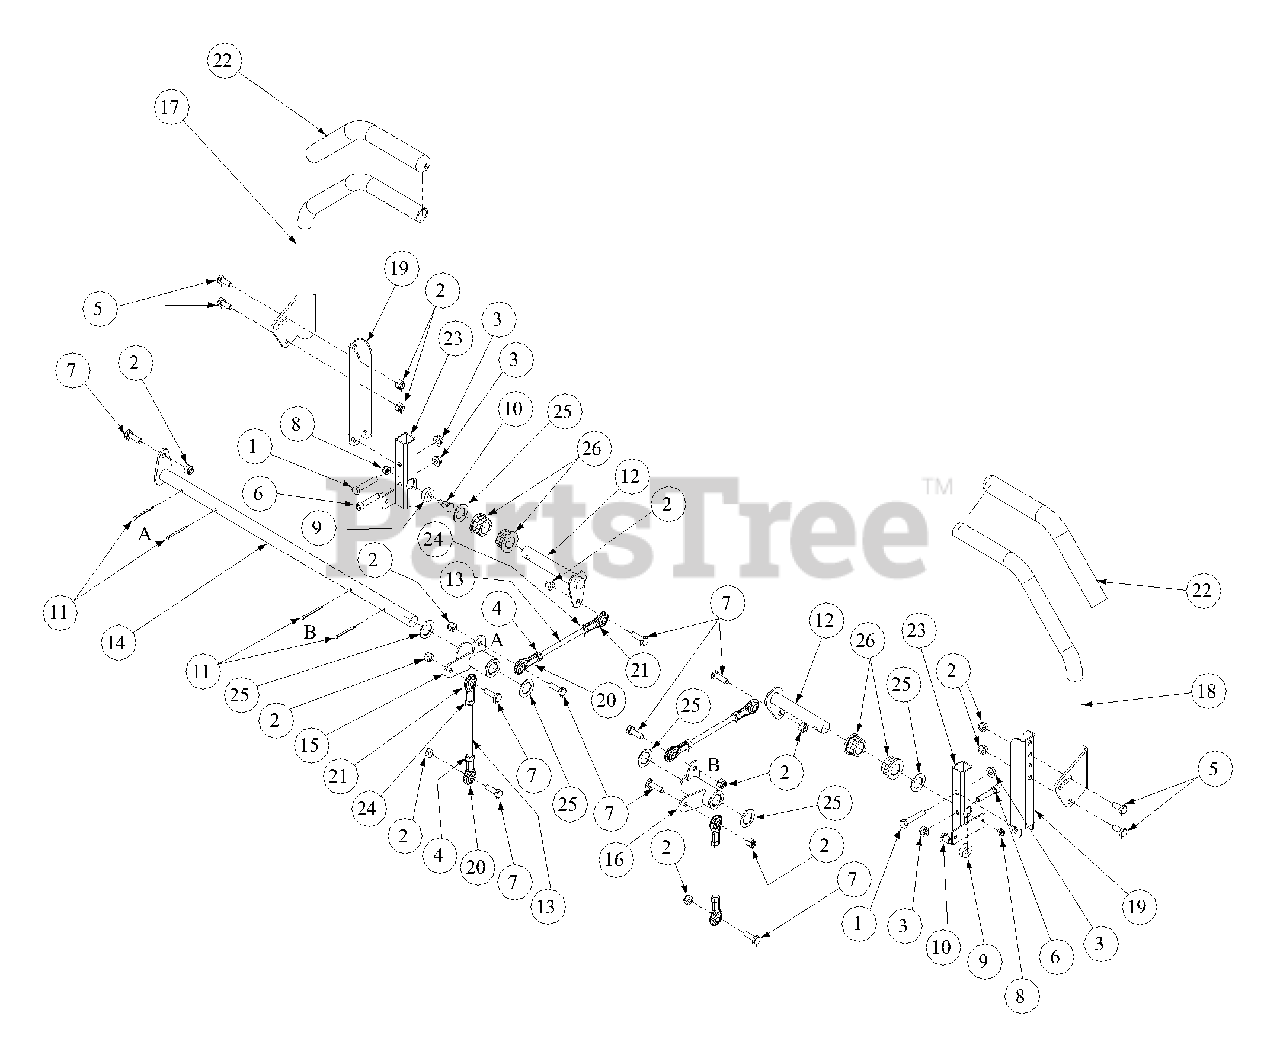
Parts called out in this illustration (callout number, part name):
1	Hex Cap Screw, 5/16-18 x 1-3/4
2	Nut, 5/16-18, Nylock
3	Nut, 5/16-18, Lock
4	Hex Nut, 5/16-24
5	Hex Cap Screw, 5/16-18 x 3/4
6	Capscrew, 5/16-18 x 1.50, Socket Head
7	Hex Cap Screw, 5/16-18 x 1.0
8	Nut, 1/4-28, SS, Nylon Insert
9	Control Rod Spacer
10	Shoulder Screw, 1/4-28
11	Cotter Pin, .125 Dia. x 1.0
12	Steering Input Shaft Assembly
13	Steering Link Rod
14	Bellcrank Steering Shaft Assembly
15	Steering Bellcrank Assembly Left Hand
16	Steering Bellcrank Assembly Right Hand
17	Steering Handle Assembly Left Hand
18	Steering Handle Assembly Right Hand
19	Steering Pivot Bracket
20	Rod End, 5/16, Right Hand
21	Rod End, 5/16, Left Hand
22	Lap Bar Grip
23	Pivot Bracket Weldment
24	Hex Nut, 5/16-24, Left Hand
25	Flat Washer, .793 ID x 1.24 OD x .060
26	Hex Flange Bearing, .752 ID
